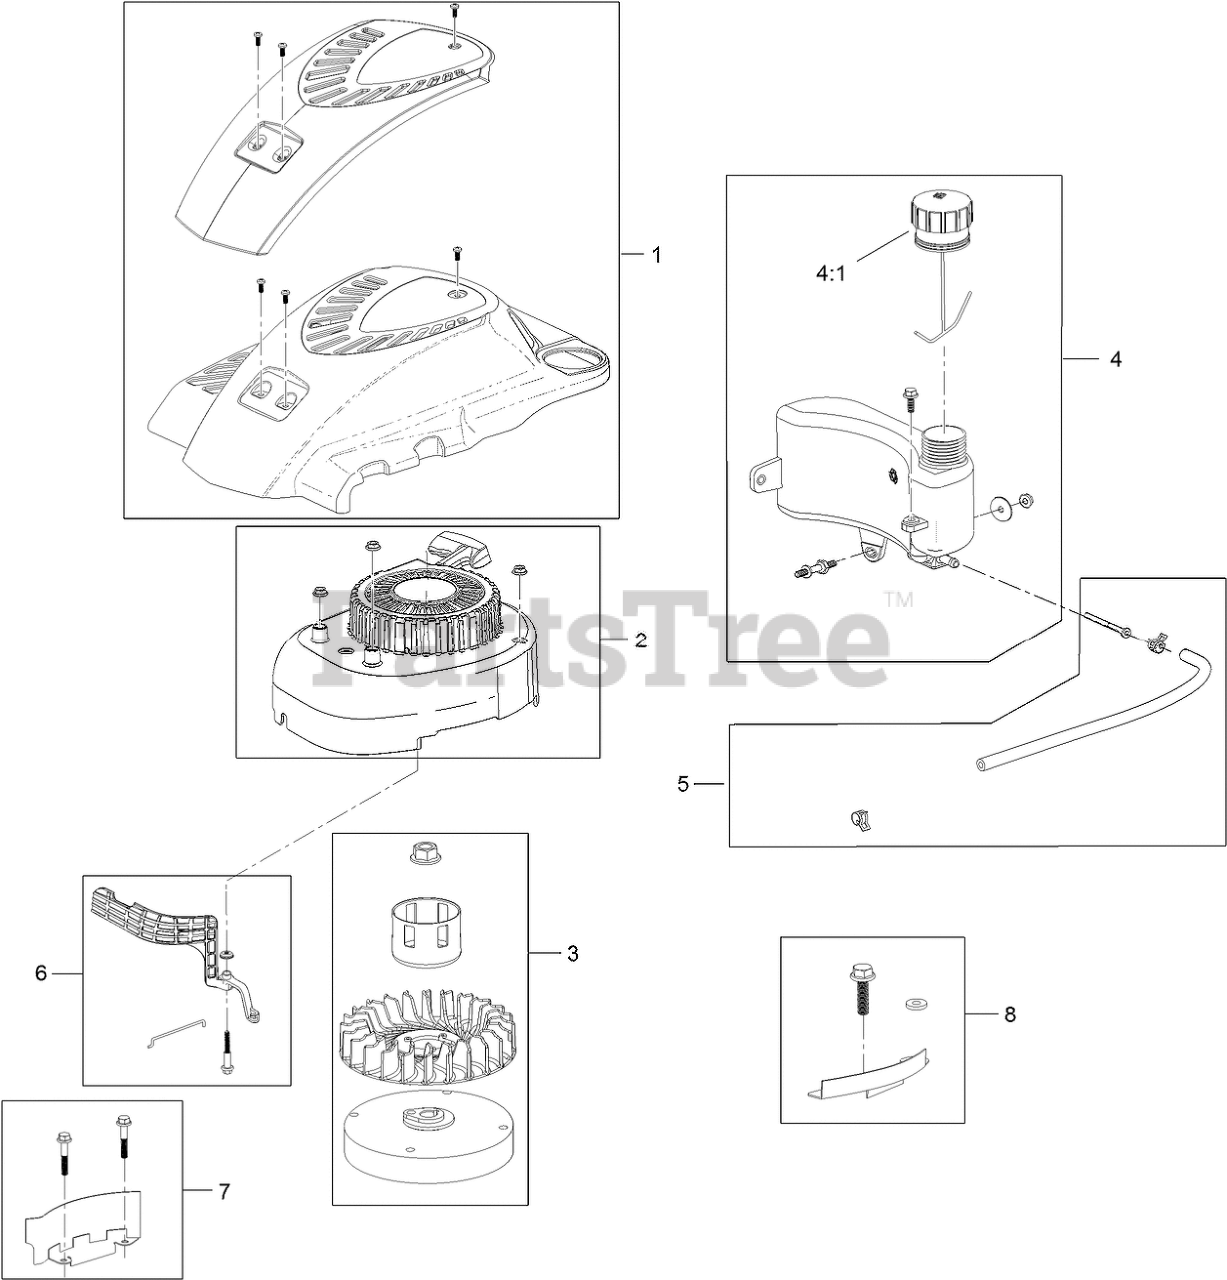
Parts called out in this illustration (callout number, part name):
1	Shroud ASM
2	RECOIL AND BLOWER SHROUD KIT
3	FLYWHEEL AND FAN KIT
4	FUEL TANK KIT
4:1	CAP-FUEL
5	FUEL LINE KIT
6	AIR VANE KIT
7	FLYWHEEL SHIELD KIT
8	FLYWHEEL GUARD KIT, BBC
